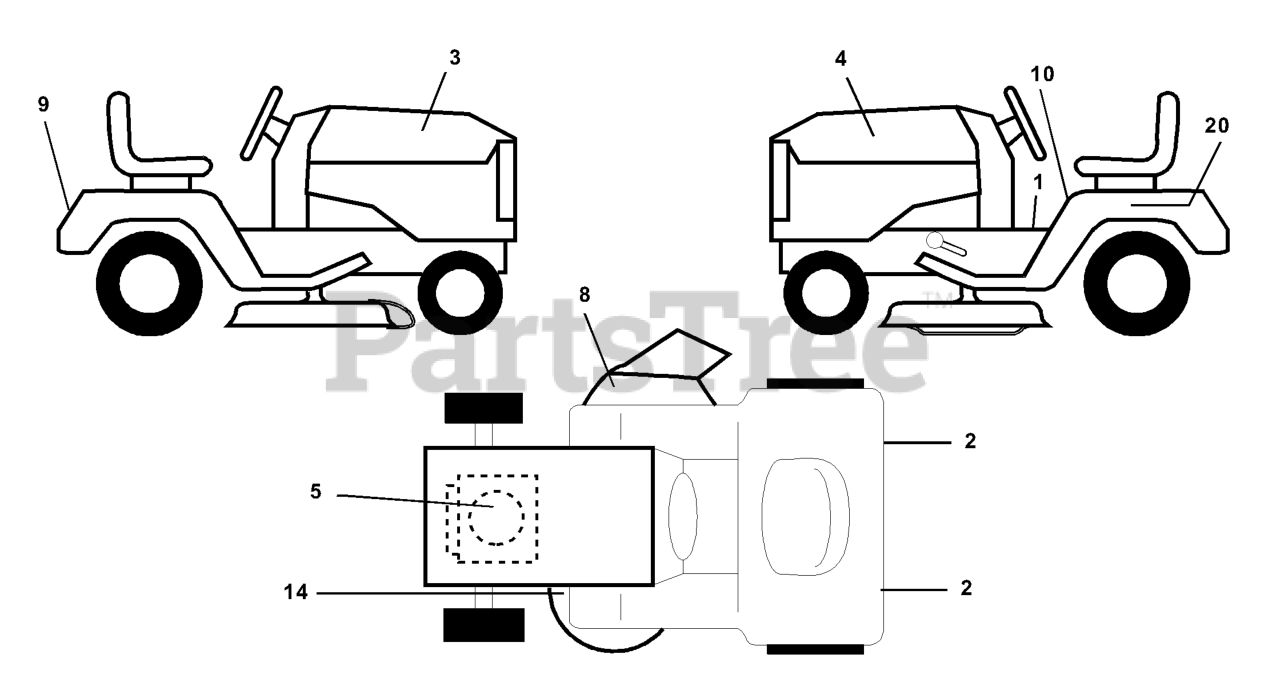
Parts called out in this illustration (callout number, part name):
2	REFLECTOR-TAIL YT
3	DECAL HOOD RH
4	DECAL HOOD LH
5	DECAL HP ENGINE
8	DECAL.WARN.KEEP.HAND.AWAY
9	DECAL, FENDER
10	DECAL FENDER DANGER
14	DECAL V BELT SCHEMATIC
20	DECAL BTRY SYMBOLS
